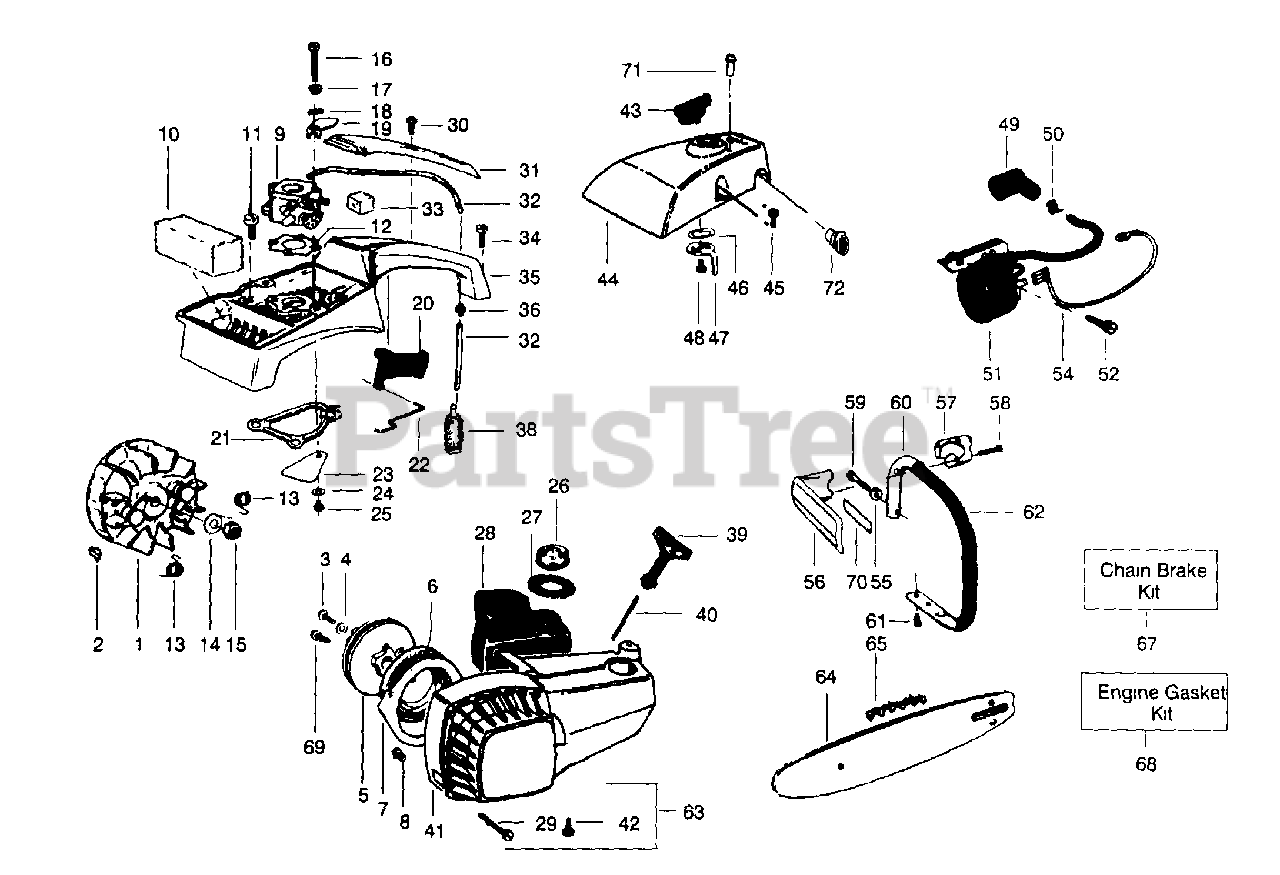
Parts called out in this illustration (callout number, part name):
1	Flywheel Ass'y
2	Flywheel Key
3	Pulley Retaining Screw
5	Starter Pulley
6	Starter Spring
7	Air Baffle - T 4
8	Screw - T 4
9	Carburetor Kit
10	Air Filter
12	Carburetor Gasket
13	Starter Dog Spring
14	Flywheel Washer
18	Wave Washer
19	Choke Shutter
20	Throttle Trigger
21	Gasket
22	Throttle Wire
23	Reed Valve
24	Washer
26	Fuel Cap Ass'y
28	Fuel Tank Ass'y
29	Screw
31	Handle Cover
32	Fuel Line
33	Throttle Wire Boot
35	Handle & Carb Hsg
36	Fuel Line Fitting
38	Fuel Pick-Up Ass'y
39	Starter Handle
40	Rope Kit
41	Fan Hsg Lt
43	Choke Knob
44	Carb Cover
46	Wave Washer
47	Choke lever
49	Spark Plug Boot
50	Spark Plug Connector
51	Ignition Module Kit
54	Switch Lead
56	Handguard
57	Handguard Cap
60	Handlebar
63	Fan Hsg. Screw Kit
64	Guide Bar
65	Chain
67	Chain Brake Kit
68	Engine Gasket Kit
69	Rope Retain Screw
70	Handguard Decal
71	Grommet - Mix
72	Grommet - Idle
